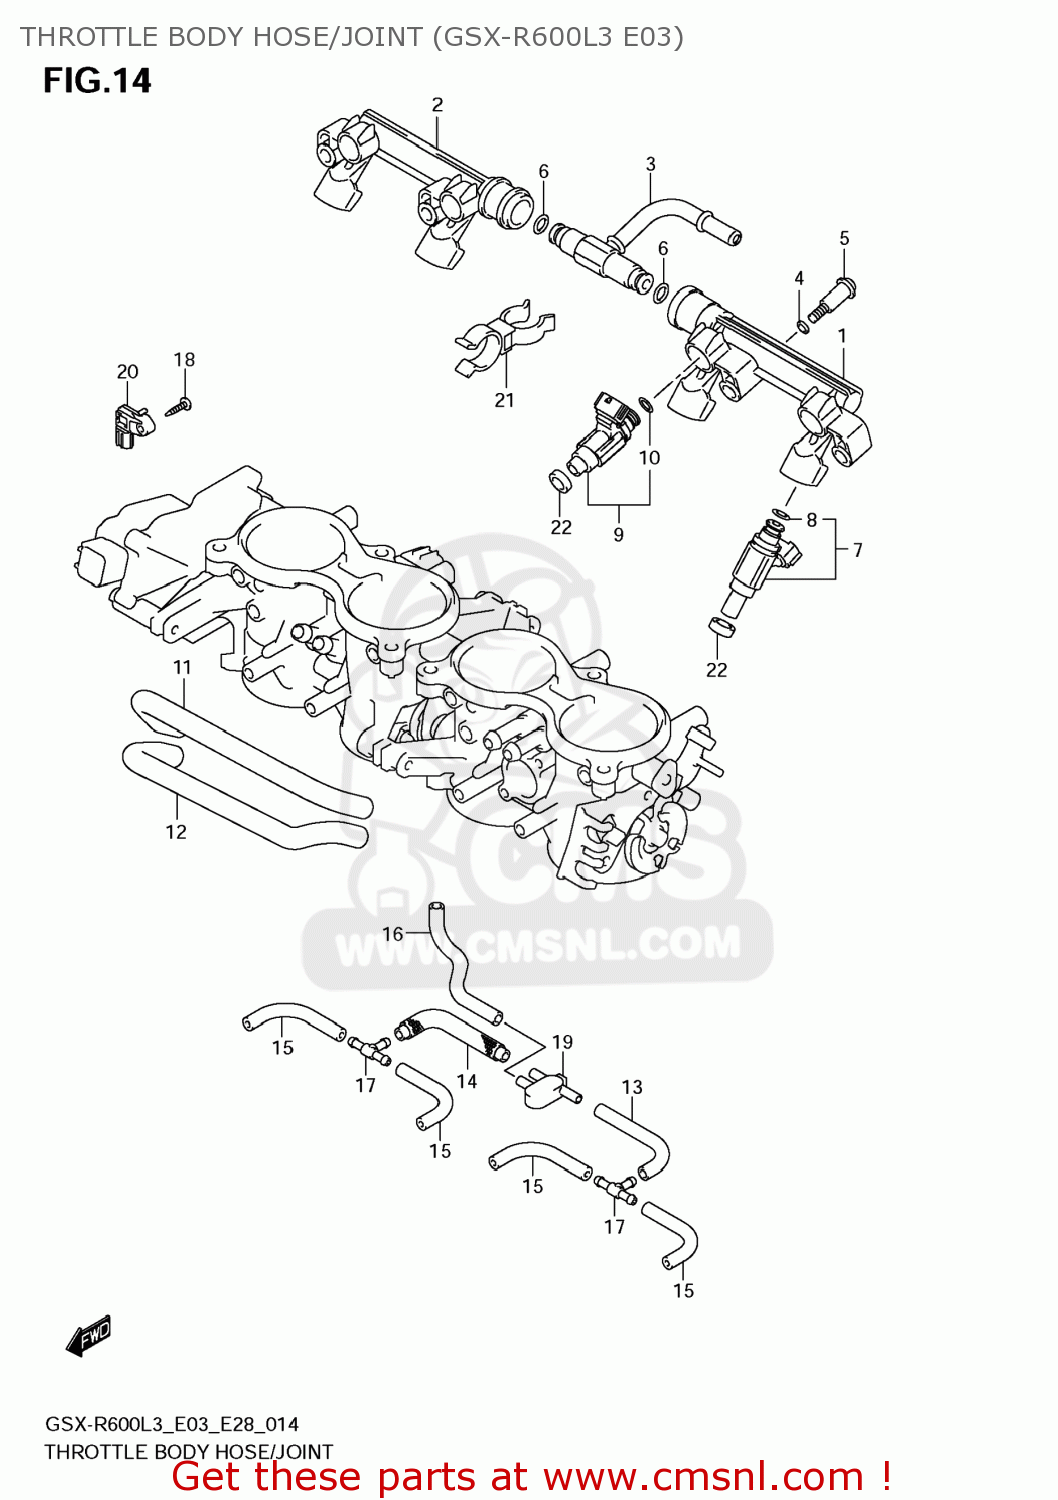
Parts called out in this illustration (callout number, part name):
1	DELIVERY PIPE
2	DELIVERY PIPE
3	NIPPLE ASSY
4	PACKING (NAS)
5	SCREW
6	O RING
7	INJECTOR ASSY
8	O-RING
9	INJECTOR ASSY
10	O-RING
11	HOSE
12	HOSE
13	HOSE
14	HOSE
15	HOSE(L:425)
16	HOSE
17	3WAY,VACUUM HOSE
18	SCREW
19	JOINT
20	SENSOR,BOOST
21	CLAMP
22	SEAL
